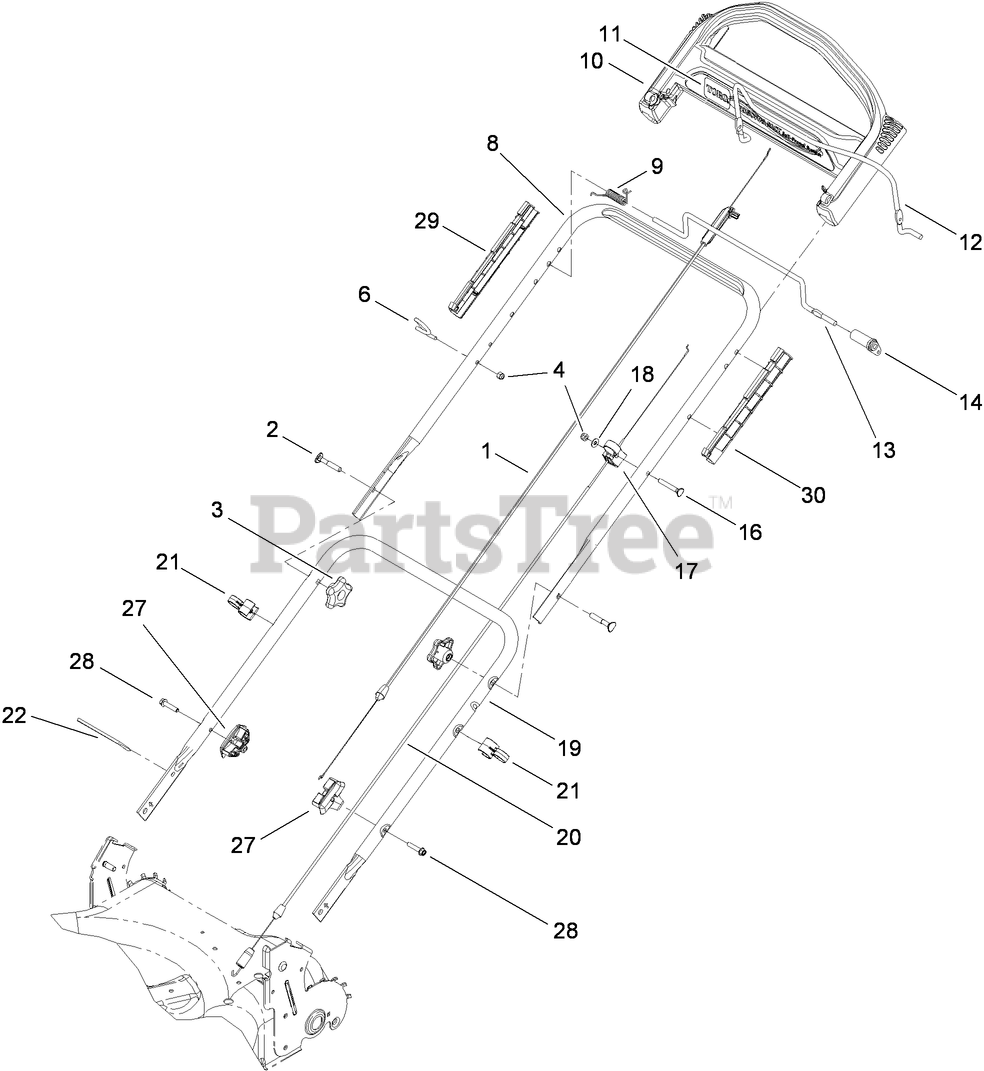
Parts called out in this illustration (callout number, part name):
1	CABLE-BRAKE
4	NUT-LOCK, NI
6	GUIDE-ROPE
8	HANDLE-UPPER
10	HANDLE-CONTROL
11	DECAL-PACE, PERSONAL
14	LEVER-TRACTION
16	SCREW
18	WASHER-FLAT
19	HANDLE-LOWER
20	CABLE-TRACTION
22	TIE-CABLE
27	ANCHOR-BAG
28	SCREW-HWH
29	GUIDE-RH
30	GUIDE-LH
